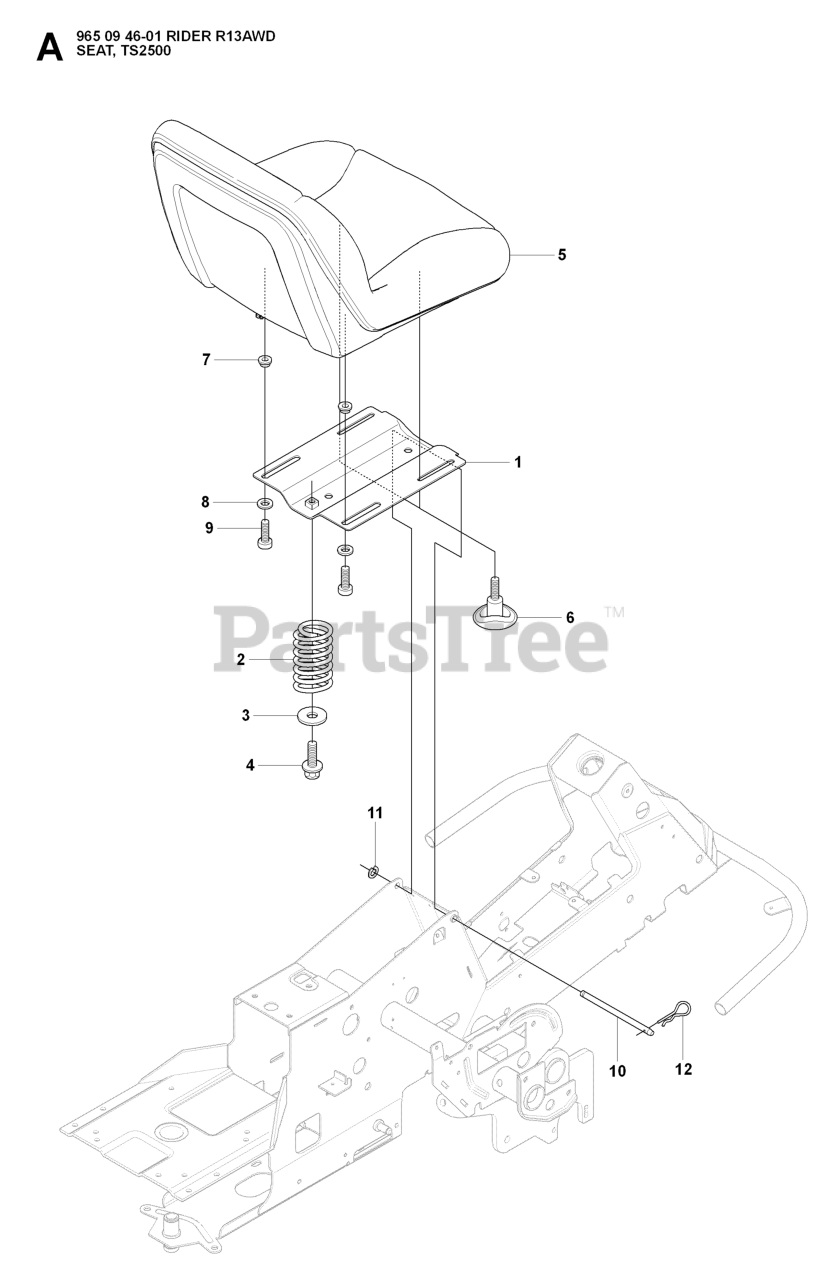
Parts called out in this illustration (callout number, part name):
1	SEAT BRACKET
2	SEAT SPRING
4	Screw M10x25
5	SEAT
6	ADJUSTING KNOB
11	RETAINING RING SGA 10
